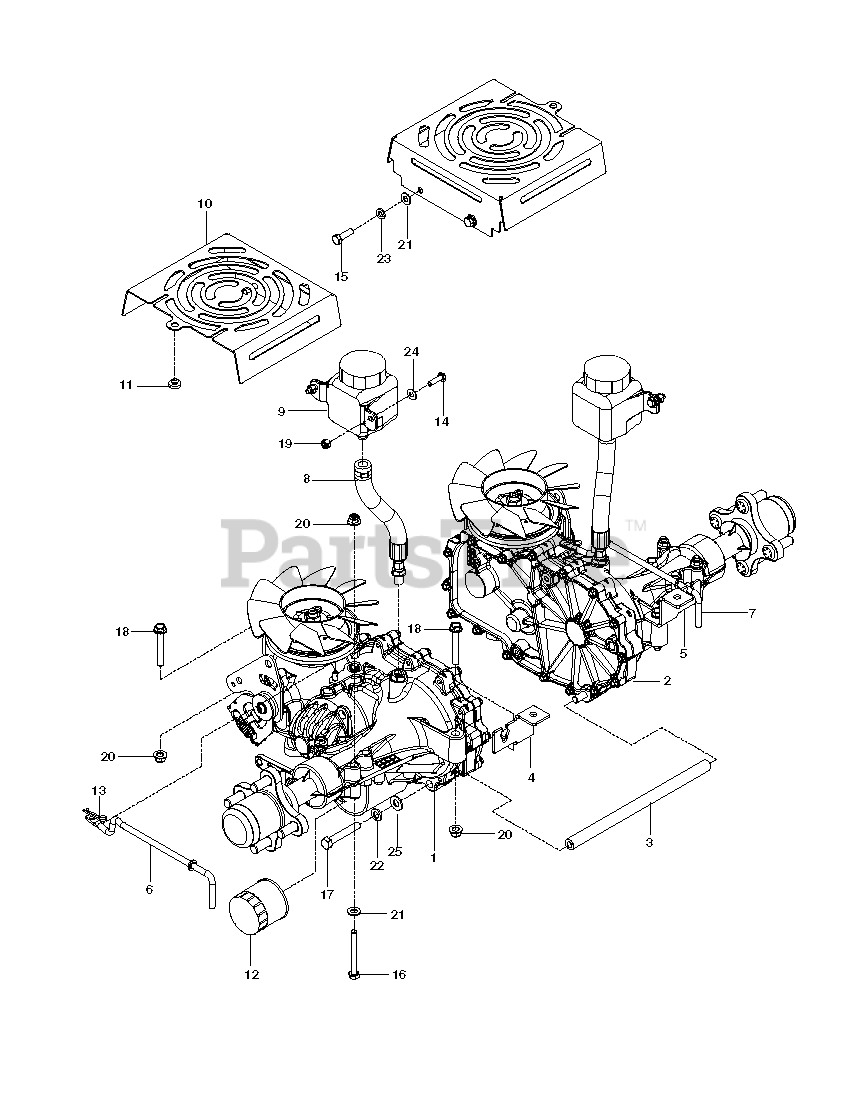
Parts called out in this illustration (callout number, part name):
1	HG_TRANS, ZT-3400, LT
2	HG_TRANS, ZT-3400, RT
3	TUBE, SPACER, 3400
4	BRACKET.TRANS.LT.BLACK
5	BRACKET, TRANS, RT BLACK
6	LINKAGE, RIGHT BYPASS
7	LINKAGE, LEFT BYPASS
8	HOSE ASSY, EXPANSION
9	TANK.EXPANSION.350ML 71328
10	SHIELD, FAN, BLK
11	GROMMET, BUMPER
12	HG_FILTER, ZT4800 52114
13	HAIRPIN #2
14	HCS 1/4-20X7/8 GR5
15	HCS 5/16C X 1
16	HCS 5/16C X 2-3/4
17	HCS 3/8-16X2-1/4 LOC PATCH GR8
18	HHFS 5/16-18 X 2.25 GD 5
19	NUT.1/4-20.HEX.NYLOC.ZD
20	5/16-18 NYLOC FLANGE NUT
21	FLAT WASHER 5/16 SAE
22	SLW 3/8 STD
23	WASHER.LOCK.HVY.HLCL.SPR.5/16
24	WASHER 1/4 SAE
25	WASHER 3/8 SAE FLAT
